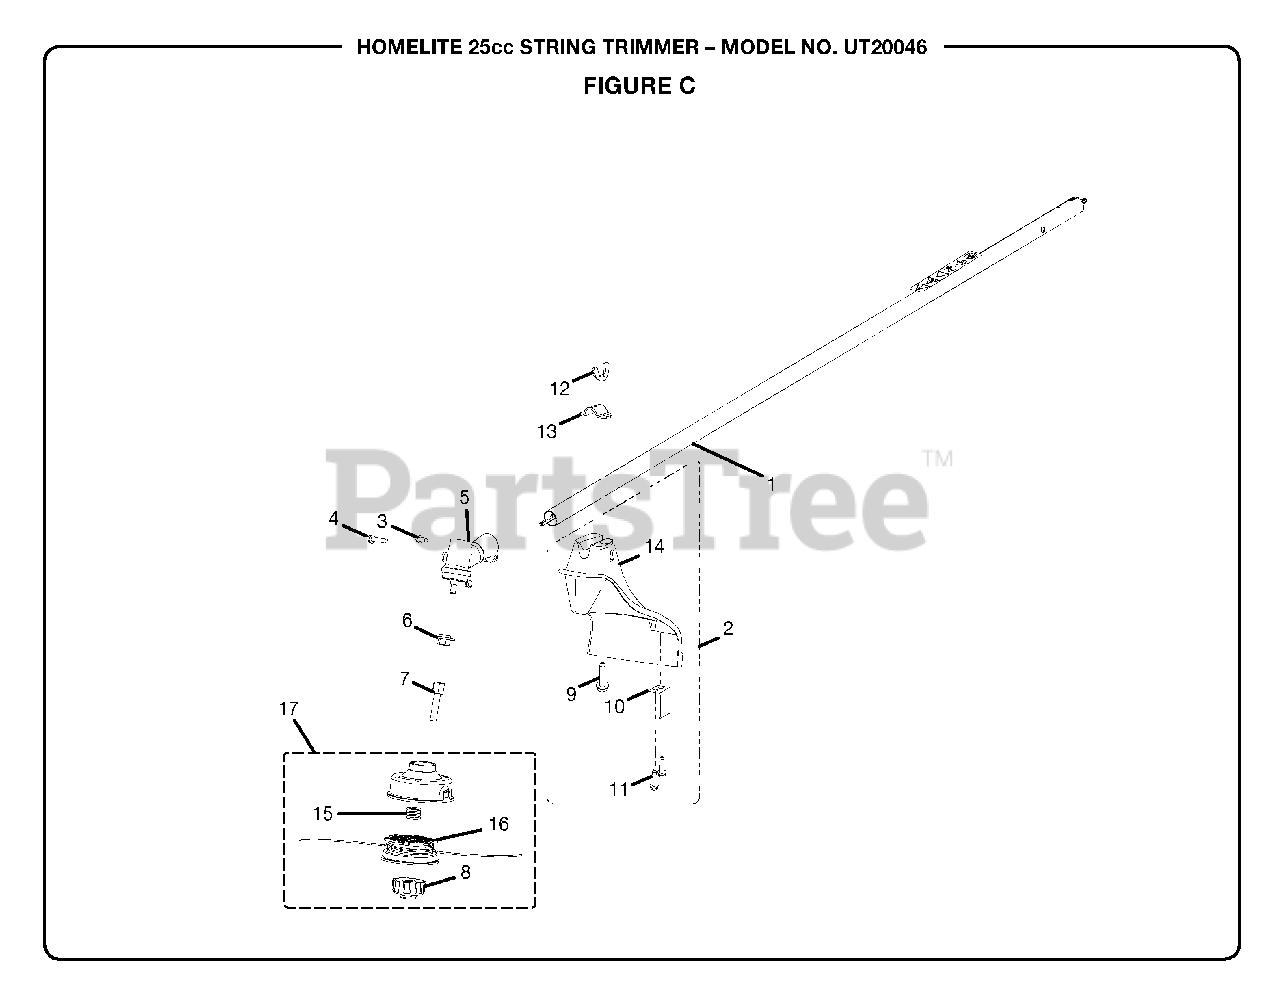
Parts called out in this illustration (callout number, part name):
1	STRAIGHT SHAFT ASSEMBLY
2	GRASS SHIELD ASSEMBLY
3	SCREW (10-24 x 5/8 in.)
4	SCREW (1/4-20 x 1-1/4 in.)
5	GEAR HEAD
7	SHAFT ADAPTER
8	SPOOL RETAINER (LH)
9	SCREW, SQUARE HEAD
10	CUT OFF BLADE
12	WING NUT
13	SHIELD CLAMP
14	GRASS SHIELD
15	SPRING
16	SPOOL & STRING (.080 in.)
17	COMPLETE STRING HEAD (.080 in.)
